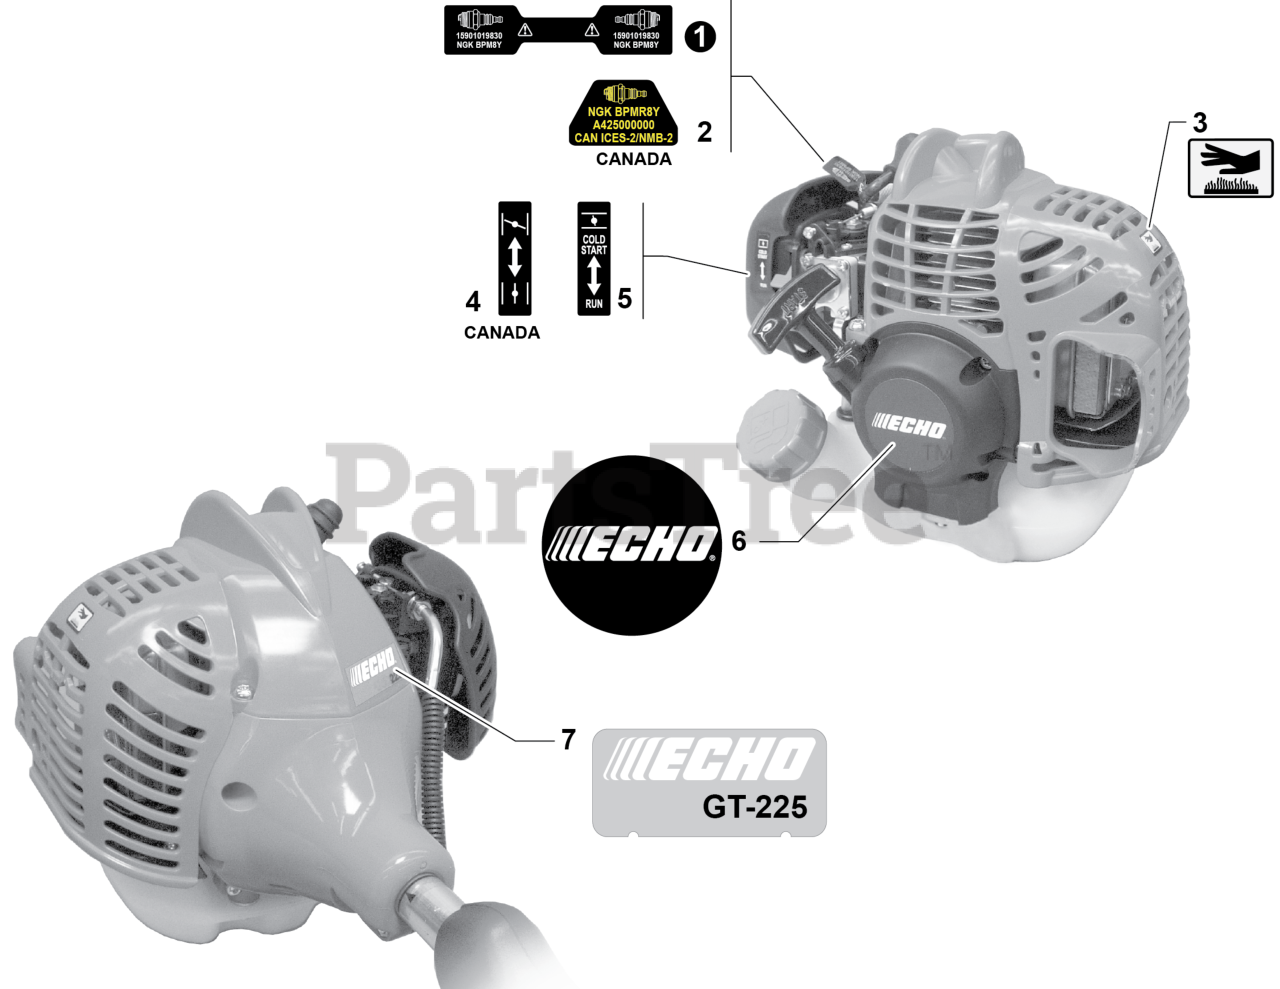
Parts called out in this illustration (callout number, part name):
1	LABEL - SPARK PLUG - BPM8Y
2	LABEL - SPARK PLUG - BPMR8Y
3	LABEL - CAUTION - HOT
4	LABEL - CHOKE
5	LABEL - CHOKE
6	LABEL - STARTER - ECHO
7	LABEL - MODEL - GT-225
